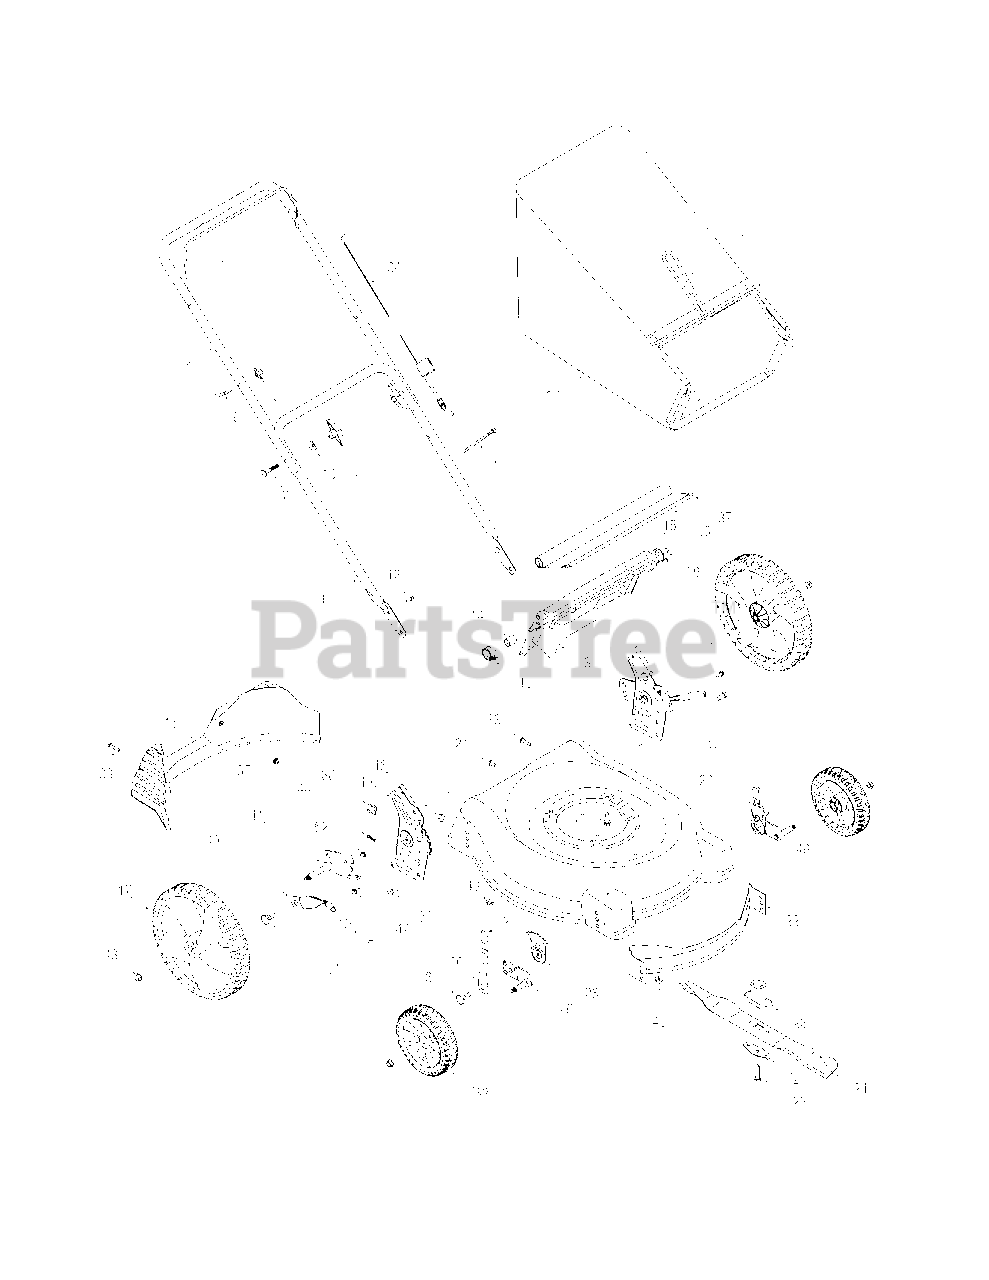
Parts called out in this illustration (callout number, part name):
1	Blade Control Handle
4	Lower Handle
5	Wing Nut
6	Rope Guide
7	Carriage Bolt ,5/16-18 x 2
8	Grass Bag Assembly
9	Hand Knob
10	Saddle Washer
11	Cable Tie
12	Carriage Bolt ,1/4-20
13	Rear Discharge Door
14	Spacer
15	Torsion Spring - LH
16	Torsion Spring - RH
17	Rear Wheel, 12" x 2.125"
18	Rear Baffle
20	Deck - 21"
21	AB Screw, 10-16 x .500"
22	Front Baffle
23	Blade Adapter
24	Mulching Blade
25	Hex Screw , 3/8-24 x 2.5
26	Pivot Arm Assembly -RH
26	Pivot Arm Assembly - LH
27	Blade Bell Support
28	Front Adjustment Plate
29	Adjustment Lever Knob
30	Spring Lever Assembly
31	Shoulder Screw
32	Front Wheel, 8" x 2.125"
33	Screw, 1/4-15 x 1.250
34	Control Cable - 40"
35	Flange Lock Nut, 1/4-20
36	Trailshield
37	Trailshield Wire
38	Wing Nut, 1/4-20
39	Rear Door Pivot Rod
40	Spring Lever
41	Pivot Arm Assembly - RH
41	Pivot Arm Assembly - LH
42	AB Screw
43	Flange Lock Nut, 3/8-16
44	Hairpin Clip
45	TT Sems Screw, 3/8-16 x 1.0
46	Ht. Adj. Assy. Front - LH
46	Ht. Adj. Assy. Front - RH
47	Rear Handle Bracket Assy. -
48	Flange Lock Nut, 3/8-16
49	Handle Bracket Assembly - RH
49	Handle Bracket Assembly - LH
50	Hex Screw, 3/8-16 x 0.75
51	Spring Lever Grip
52	Screw, 1/4-20 x .500
